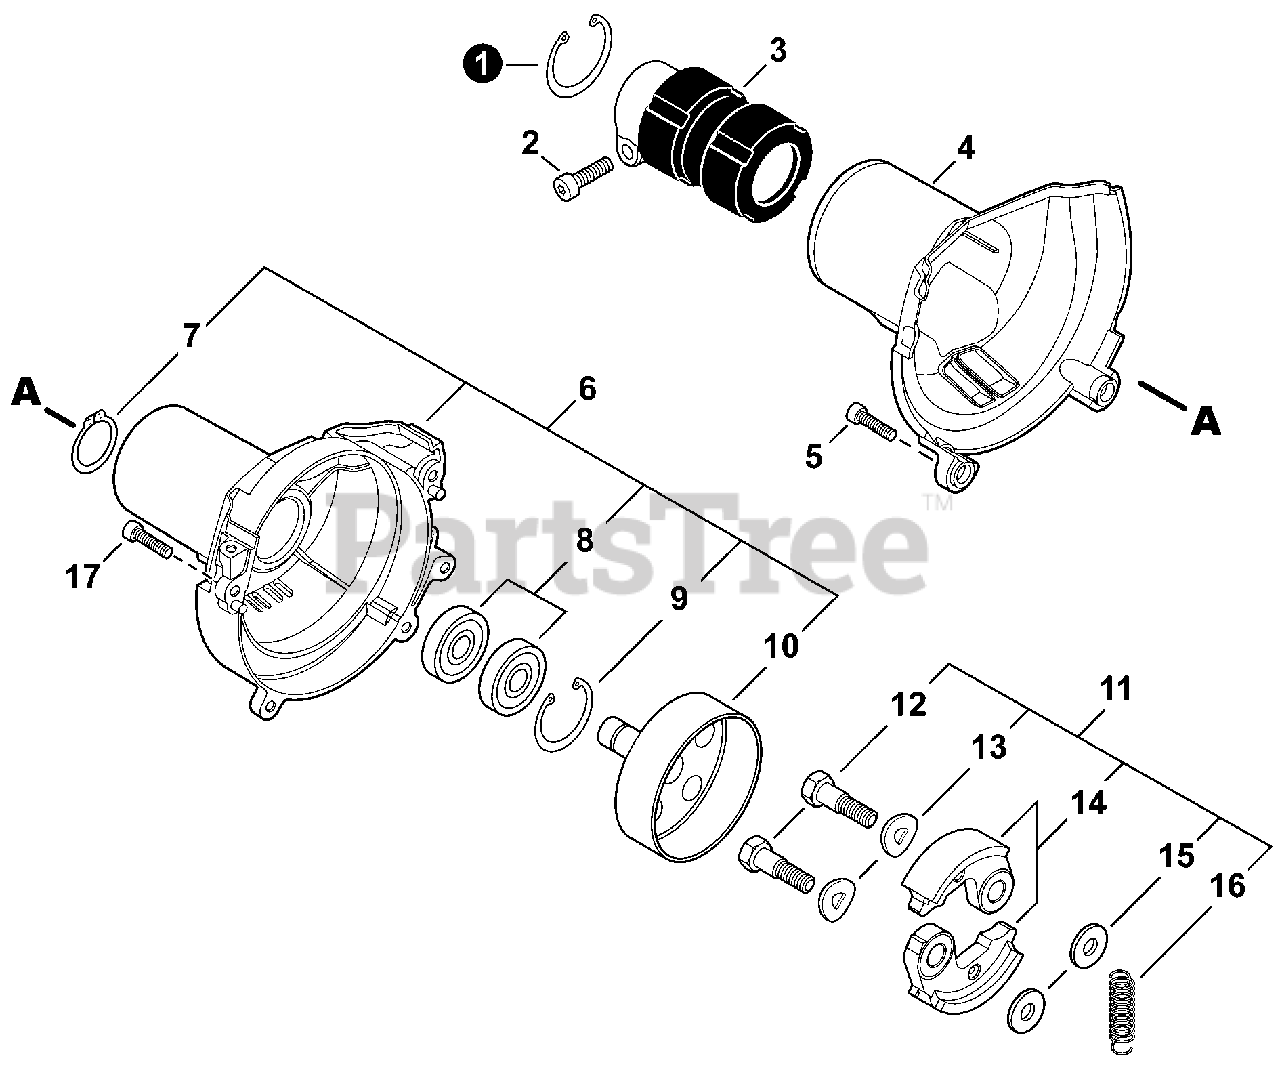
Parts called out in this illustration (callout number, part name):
1	RING, SNAP 42
2	BOLT, TORX 5×25
3	HOLDER, MAIN PIPE
4	PROTECTOR, FAN COVER
5	BOLT, TORX 5×20
6	COVER ASSY, FAN
7	RING, SNAP 12
8	BEARING, BALL 6001
9	RING, SNAP 28
10	DRUM, CLUTCH
11	CLUTCH ASSY
12	BOLT, CLUTCH 8×7.9×M6
13	WASHER 8.5×16×0.5
14	SHOE, CLUTCH
15	WASHER 6.2×19×1.0
16	SPRING, CLUTCH
17	BOLT, TORX 5×16
